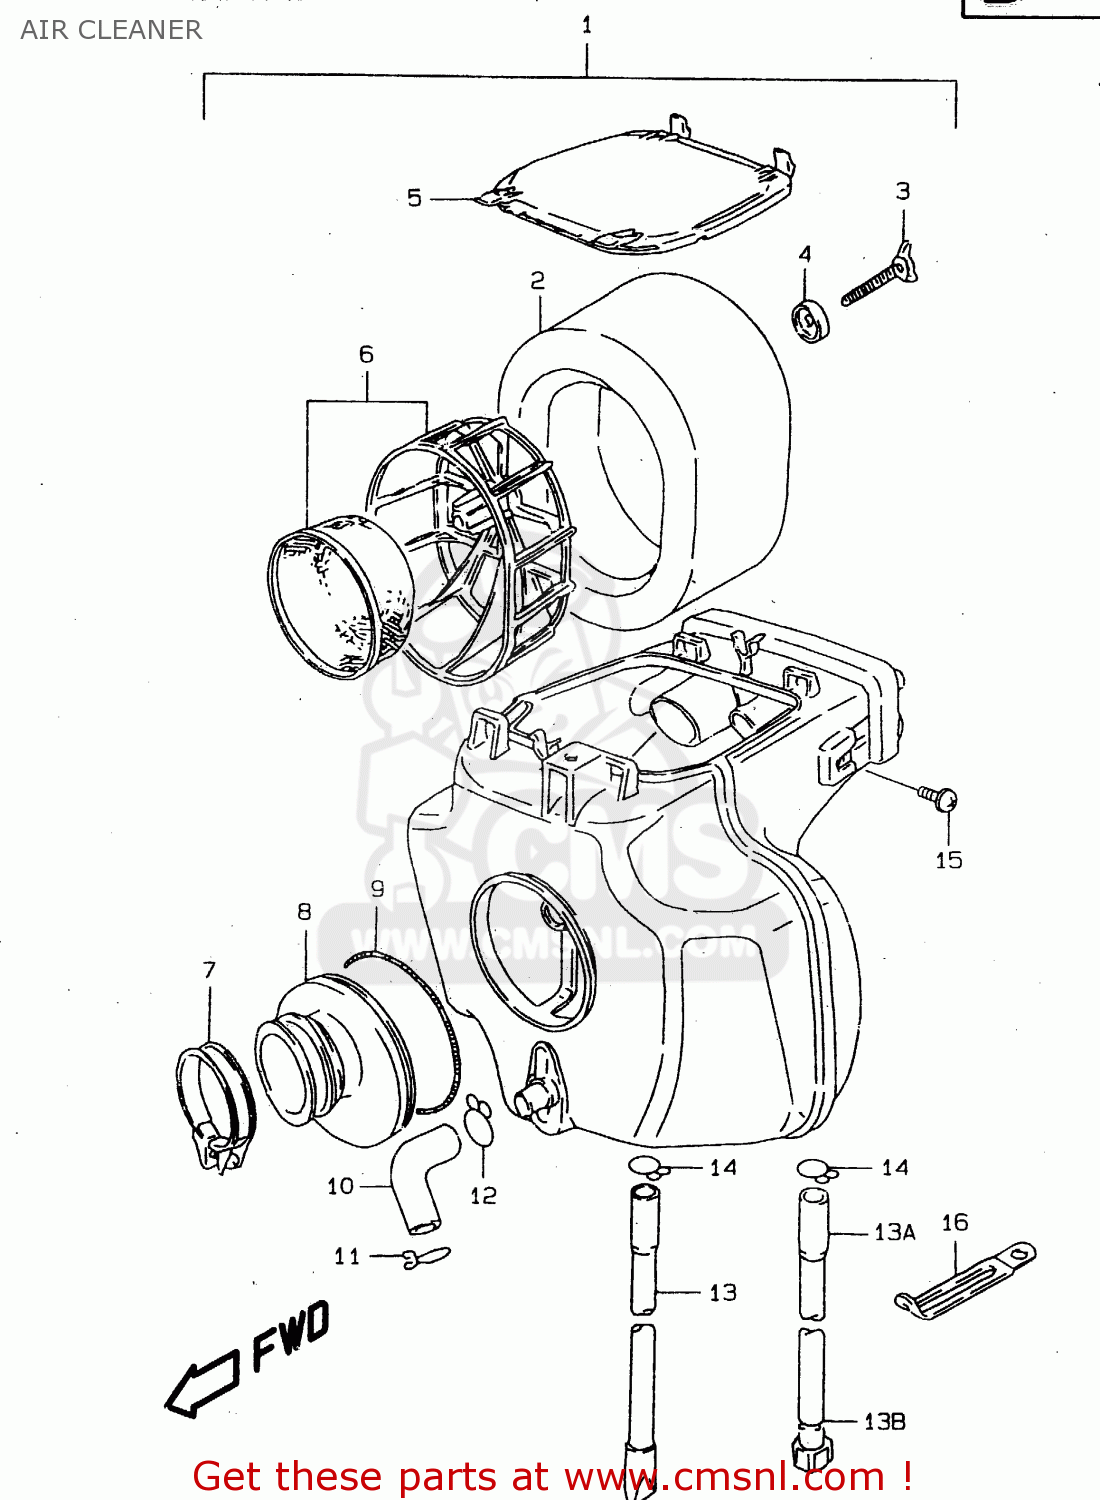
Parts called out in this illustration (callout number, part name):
1	CLEANER ASSY, AIR
2	FILTER
3	BOLT,WING
4	WASHER,FILTER HOLDER
5	CAP
6	HOLDER
7	CLAMP
8	TUBE,AIR CLEANER OUTLET
9	CLAMP,AIR CLEANER SIDE
10	TUBE,BREATHER
11	CLIP
12	CLIP
13	DRAIN TUBE
13A	TUBE,DRAIN
13B	CLIP
14	CLIP
15	SCREW
16	CLAMP(L:80)
